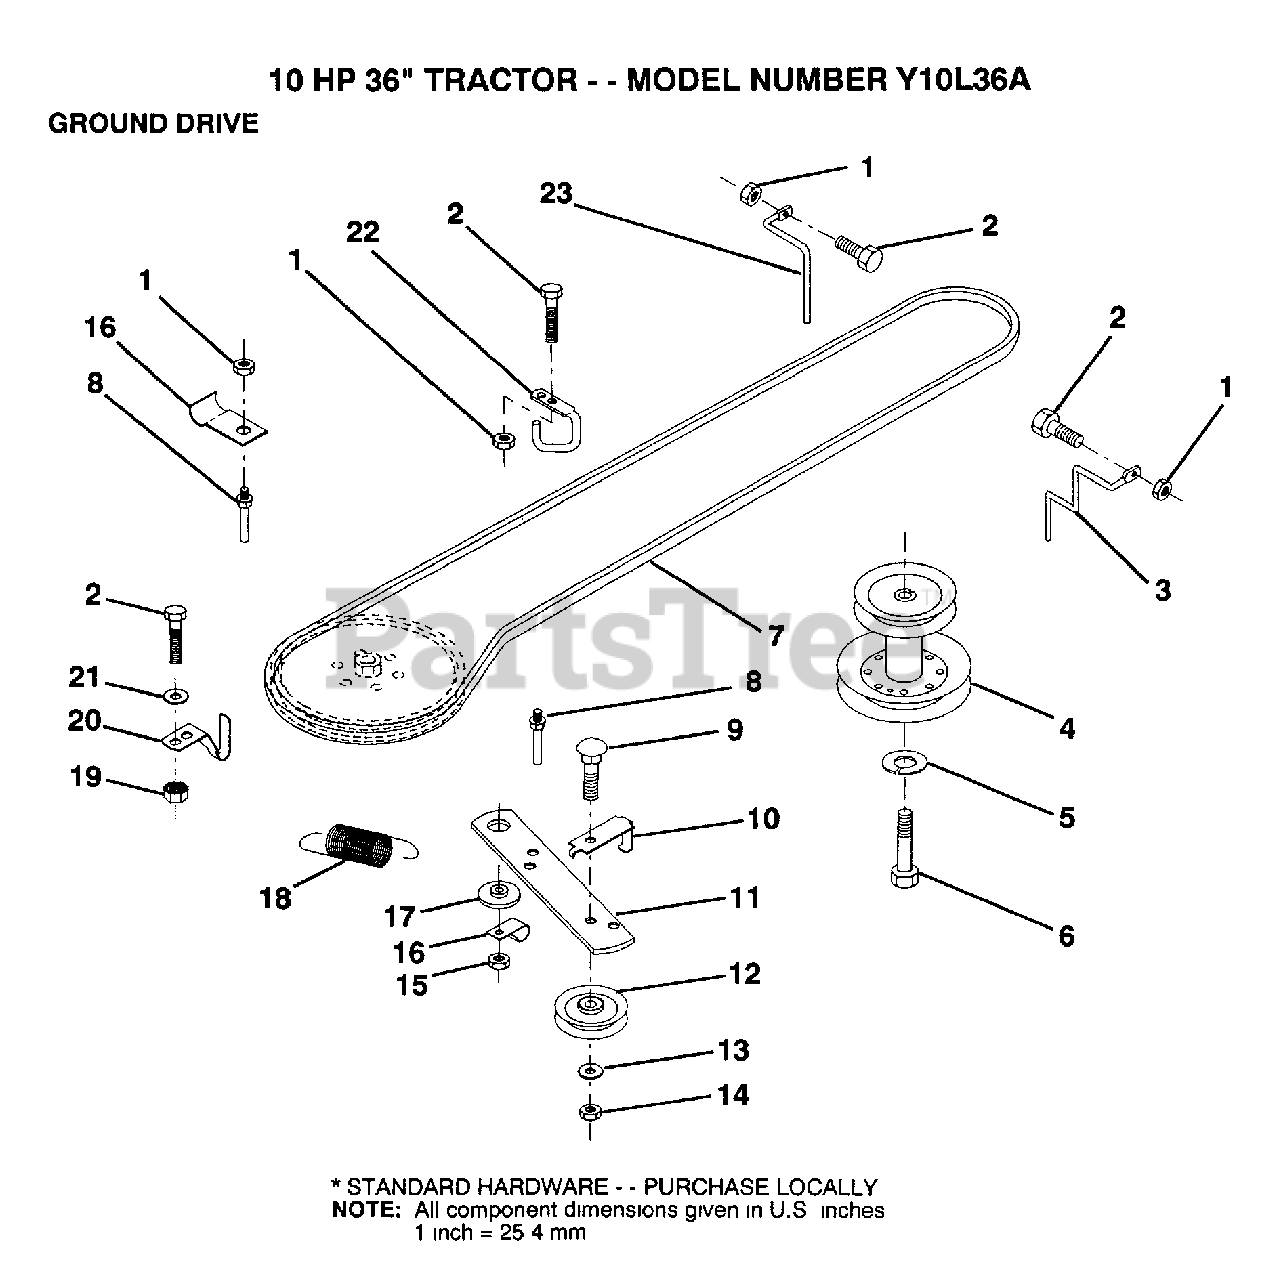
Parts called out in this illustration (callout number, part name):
2	BOLT
5	LOCKWASHER
6	HEX BOLT
7	BELT
8	"KEEPER,DRIVE BELT"
9	BOLT
10	"KEEP,IDLER DR BEL"
13	WASHER
14	LOCKNUT
16	"CLIP,INSULATOR"
17	SPACER RETAINER
20	"KEEPER,DR BELT "
21	WASHER
22	"KEEPER,FRA DR BEL"
